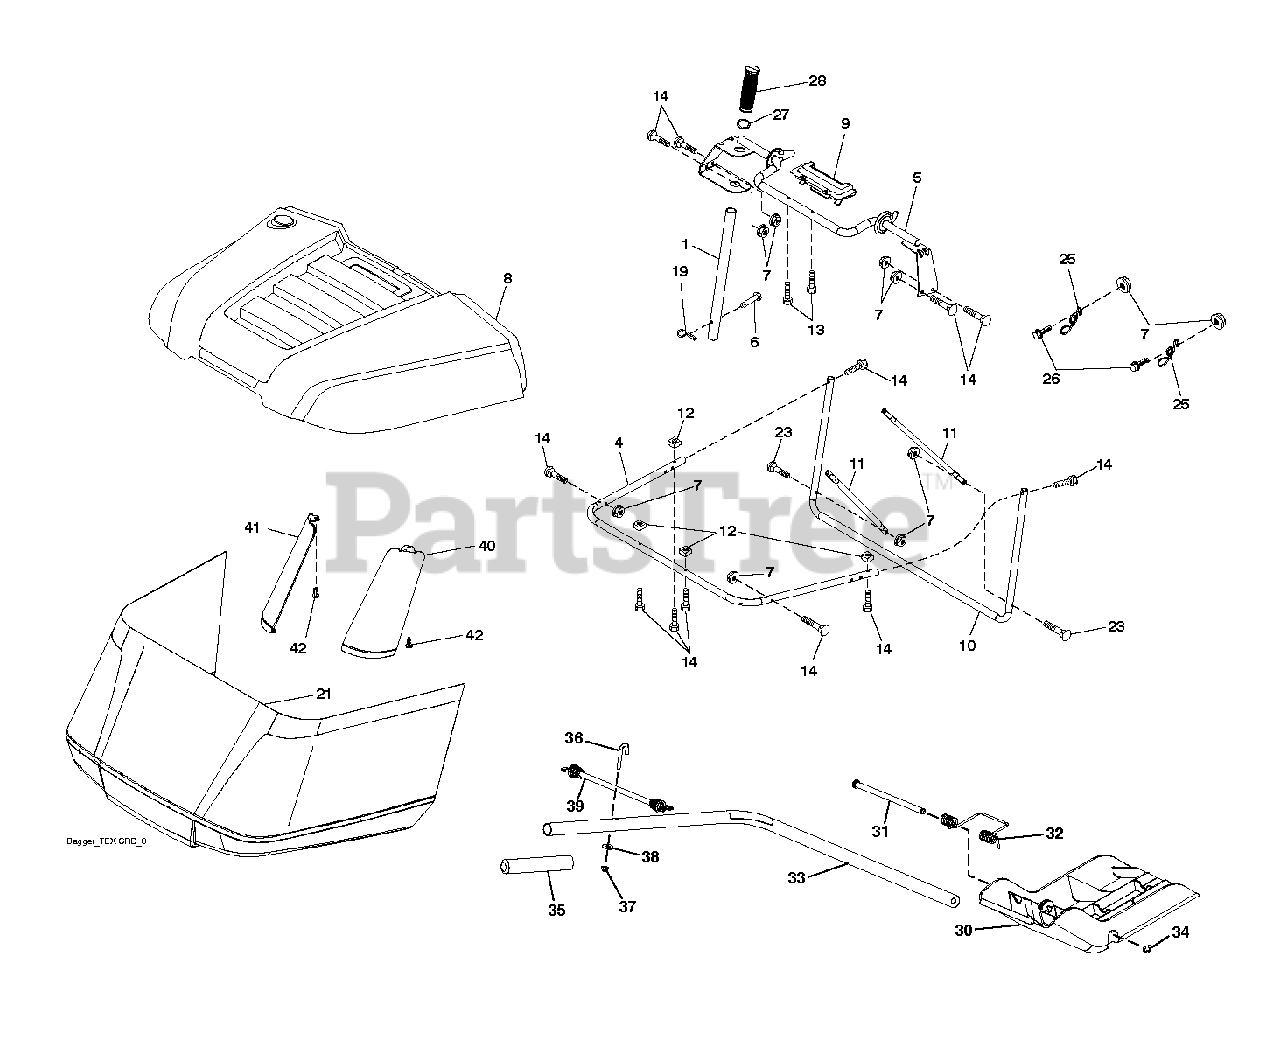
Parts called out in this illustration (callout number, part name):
1	TUBE.PNT.HDL.BAGGER.
6	RIVET,DRILLED
7	NUT T
19	PIN.COTTER.5/16.BOW TI
26	SCREW HEX CRT
28	GRIP.HANDLE.BLACK
34	E-RING.5/16"
38	WASHER
